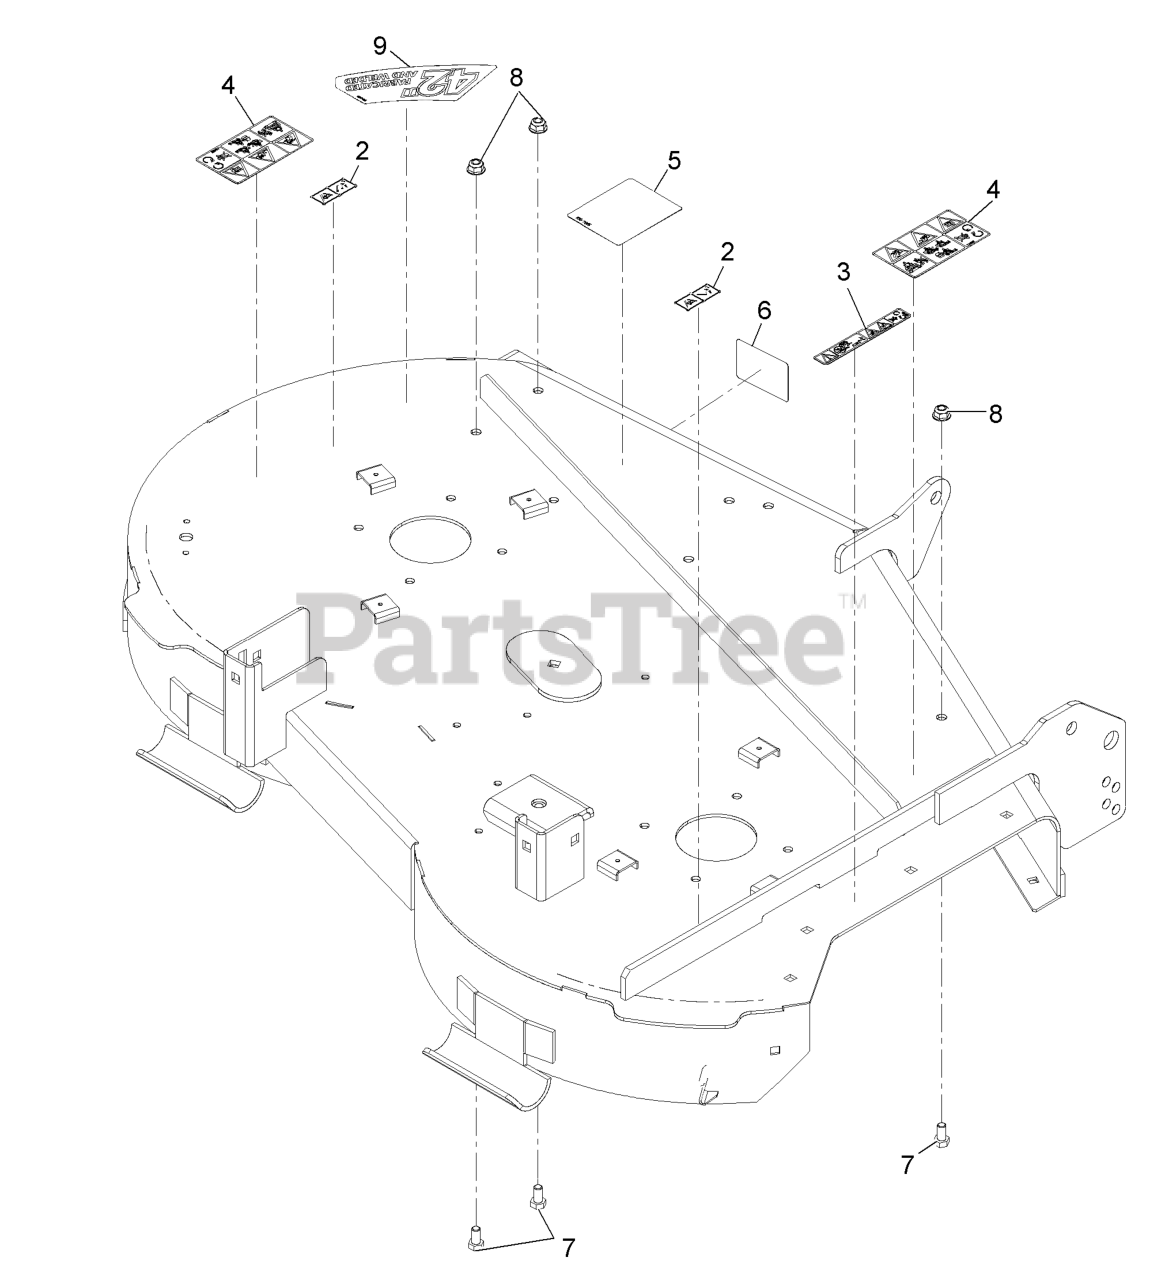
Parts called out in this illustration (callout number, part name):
2	DECAL-DANGER
3	DECAL-DANGER
4	DECAL-DANGER
5	DECAL-ROUTING, BELT
6	DECAL-SCALP, ANTI
7	SCREW-HH
8	NUT-HF, NI
9	DECAL-42 INCH
